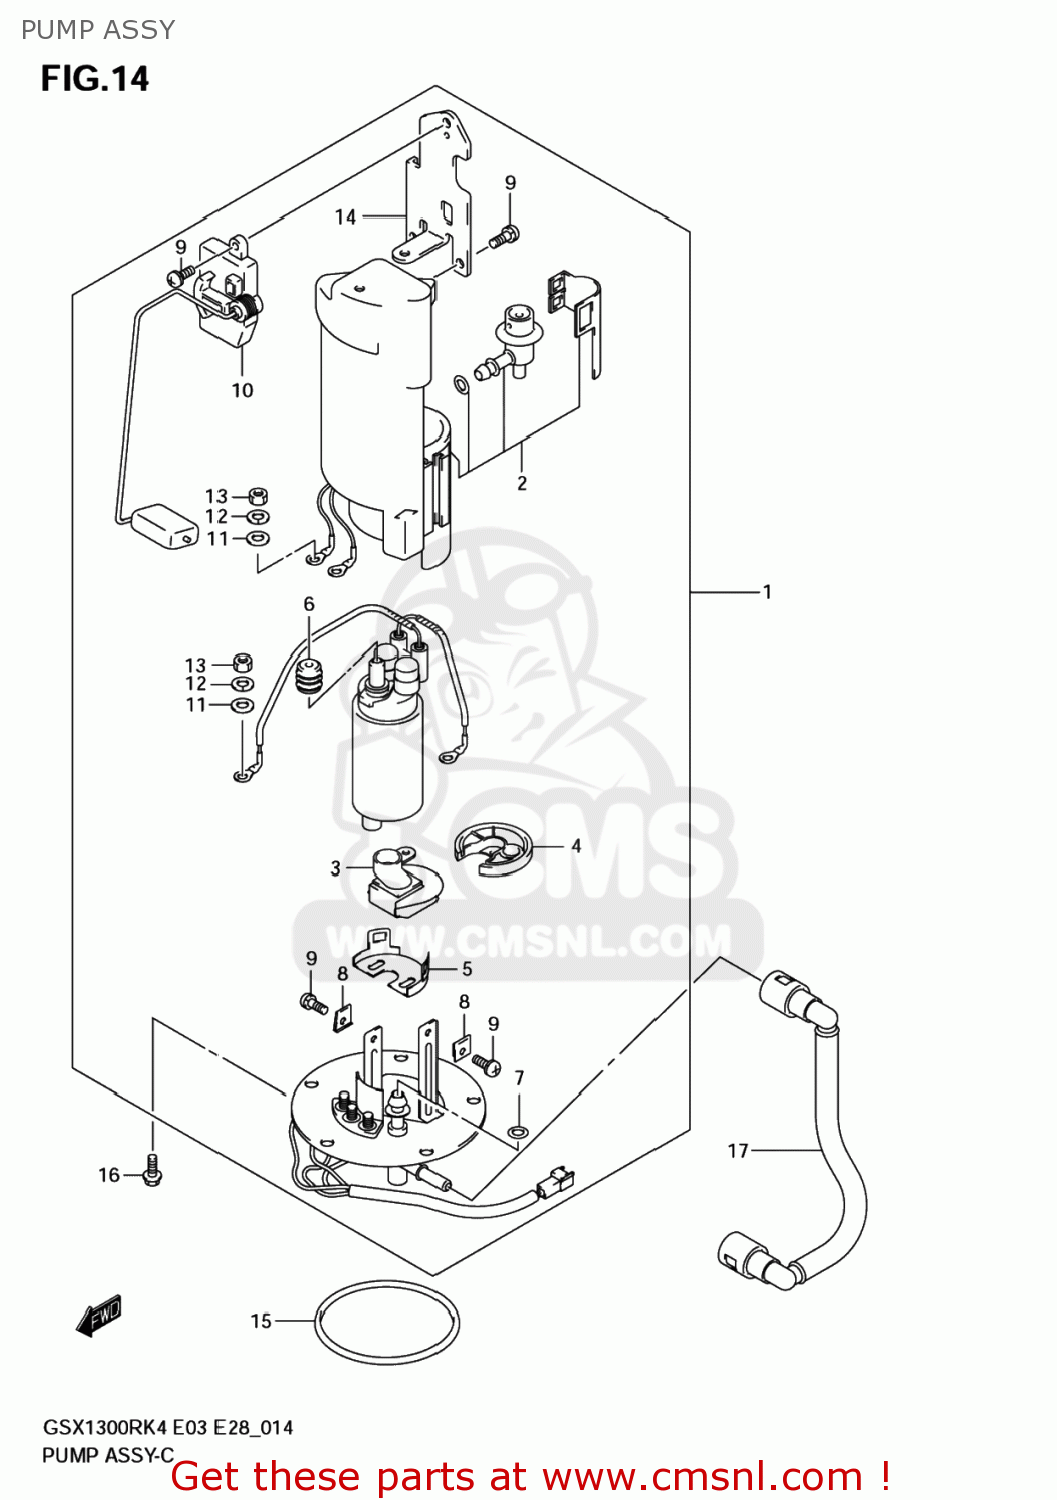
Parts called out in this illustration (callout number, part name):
1	PUMP ASSY,FUEL
2	FILTER,FUEL
3	STRAINER,FUEL PUMP
4	CUSHION
5	HOLDER,FUEL PUMP
6	BUSH,FUEL PUMP
7	O RING
8	NUT
9	SCREW
10	GAUGE ASSY,FUEL LEVEL
11	WASHER
12	WASHER,SPRING
13	NUT
14	BRACKET,FUEL GAUGE
15	O RING,FUEL PUMP
16	BOLT
17	HOSE,FUEL
